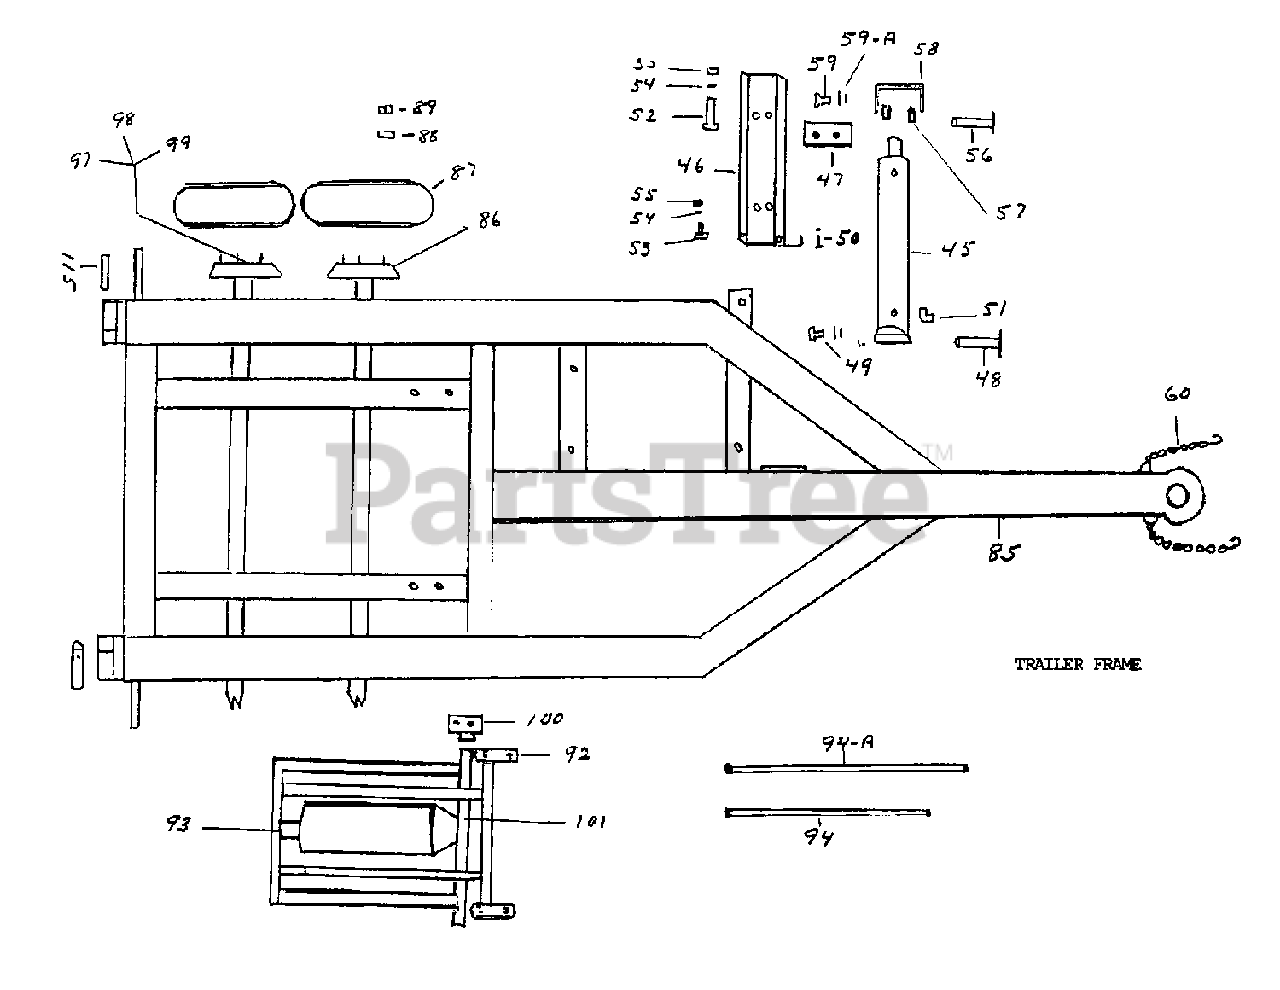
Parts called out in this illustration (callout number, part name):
45	Hydraulic cylinder – 24 (hydraulic jack leg)
46	Cylinder mounting bracket
47	Cylinder clamp bracket
48	Cylinder top mounting pin – 1-1/4 x 7
49	1/2-13 x 1-1/4 bolt/lockwasher/flatwasher
50	3/8 x 2 clevis pin & bridge pin
51	Hydraulic fitting – Tompkins 2501-6-8
52	1/2-13 x 5-1/2 hex bolt (clamp bolt)
53	5/8-11 x 1-1/2 hex bolt
54	5/8 flat washer (modified – ‘D’ shape)
55	5/8-11 hex nut
56	Jack foot pin – 1-1/4 x 5
57	1-1/4ID x 3/4 spacer
58	Jack foot
59	1/2-13 x 1-1/4 bolt/lockwasher/flatwasher
59A	5/8 flat washer
60	Safety chain (set of 2)
85	Trailer frame
86	Axle and spring assy
87	Tire & rim assy – 8-14.5LT
92	Hoist box brackets
93	Hoist assembly – complete
94	Hydraulic hose – 1/2 x 123
94A	Hydraulic hose – 1/2 x 143
98	Bearing seal
99	Bearing
100	Hoist trailer bracket
101	Hoist pin
115	Tail light assembly with mounting ring
